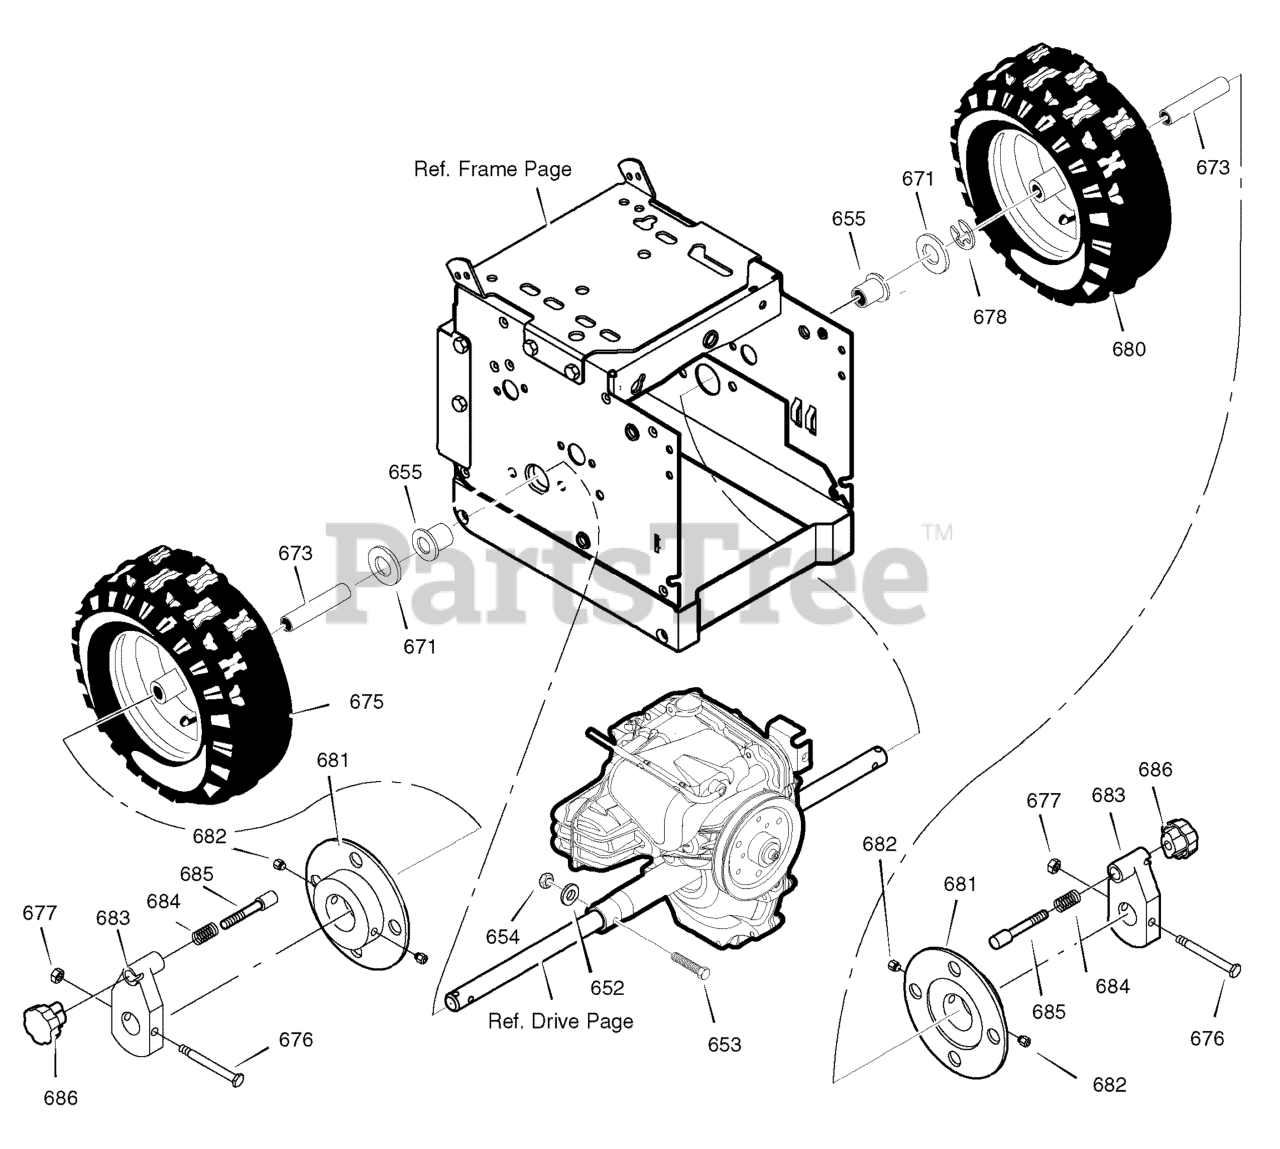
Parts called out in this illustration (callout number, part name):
652	SPACER
653	SCREW, 1/4-20 X 1.75
654	NUT, 1/4-20
655	BEARING, AXLE
671	FLATWASHER
673	BUSHING, WHEEL
675	TIRE & RIM, RIGHT
676	SCREW, 1/4-20 X 2.25
677	NUT, 1/4-20
678	RING, RET
680	TIRE & RIM, LEFT
681	DISC, WHEEL
683	HUB, WHEEL LOCK
685	PIN, LOCK
687	DECAL, WHEEL LOCK PICTORIAL
